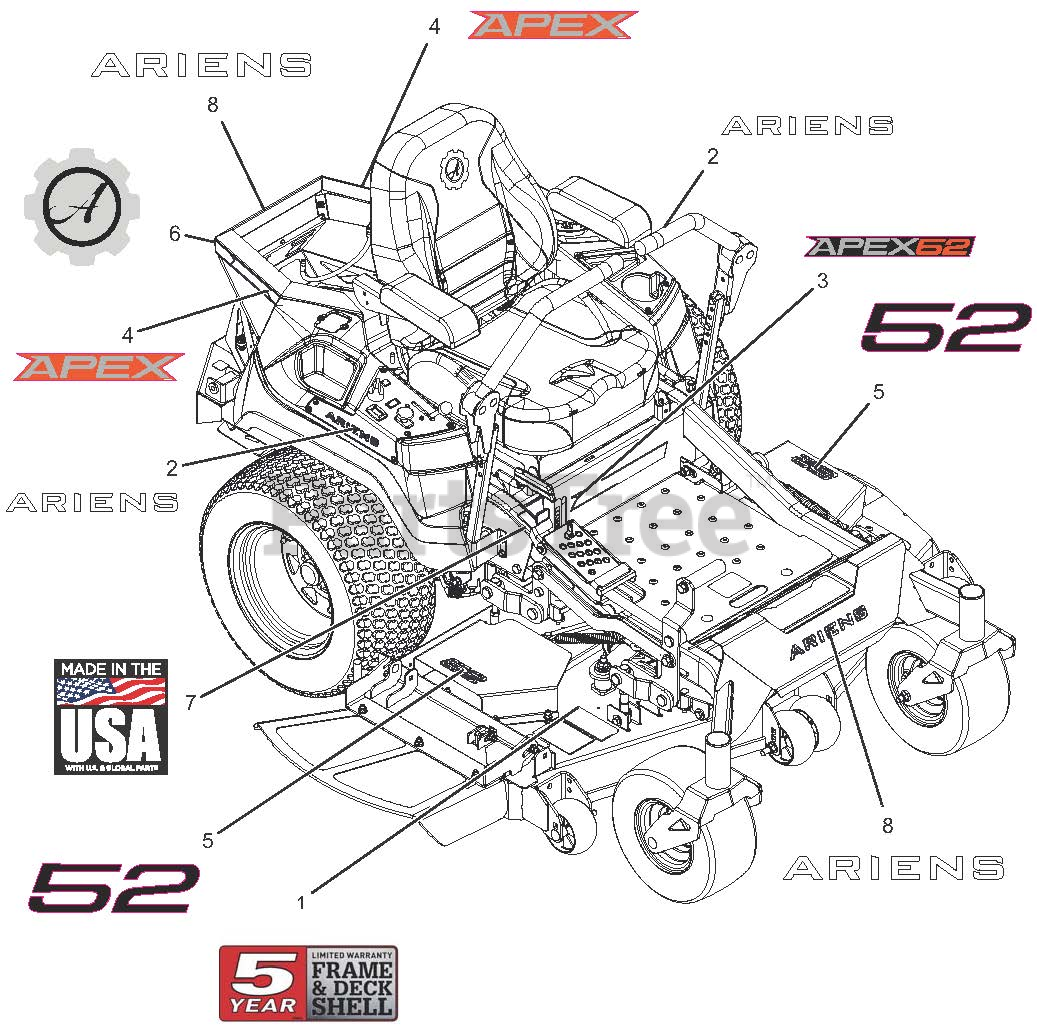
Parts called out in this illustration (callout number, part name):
1	DECAL-ARIENS, DECK 5 YEAR
2	DECAL, ARIENS (6.50")
3	DECAL, 52" APEX KICKPLATE
4	DECAL, APEX FENDER
5	DECAL, BLACK 52
6	DECAL, ARIENS-GEAR BADGE -THK
7	DECAL, MADE IN USA
8	DECAL - ARIENS 9.625"
9	DECAL, DASH DECAL
